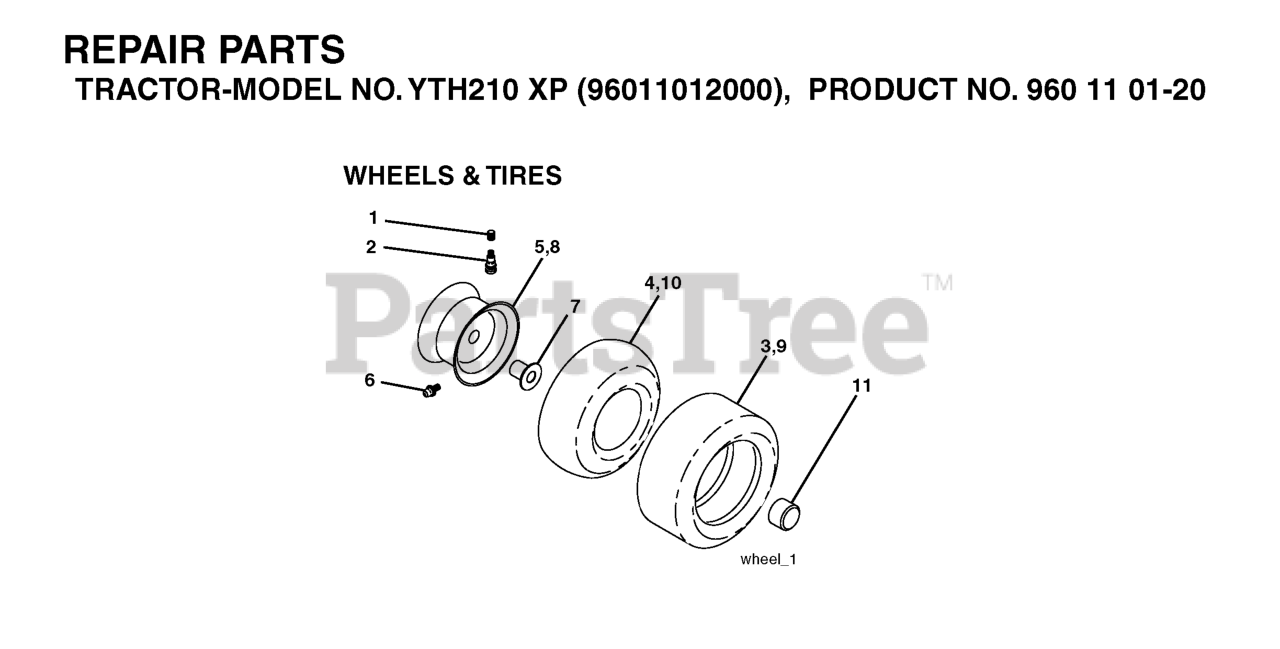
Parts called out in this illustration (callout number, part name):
2	VALVE STEM LT
3	TIRE HEAVY DUTY
4	TUBE.5.3/4.5/6
5	RIM ASM 6" FRONT SILVER
6	FITTING LT
7	BEARING T
8	RIM ASM 8" REAR SILVER
9	TIRE.TS.20X10-8
10	TUBE
11	CAP, AXLE BLK
